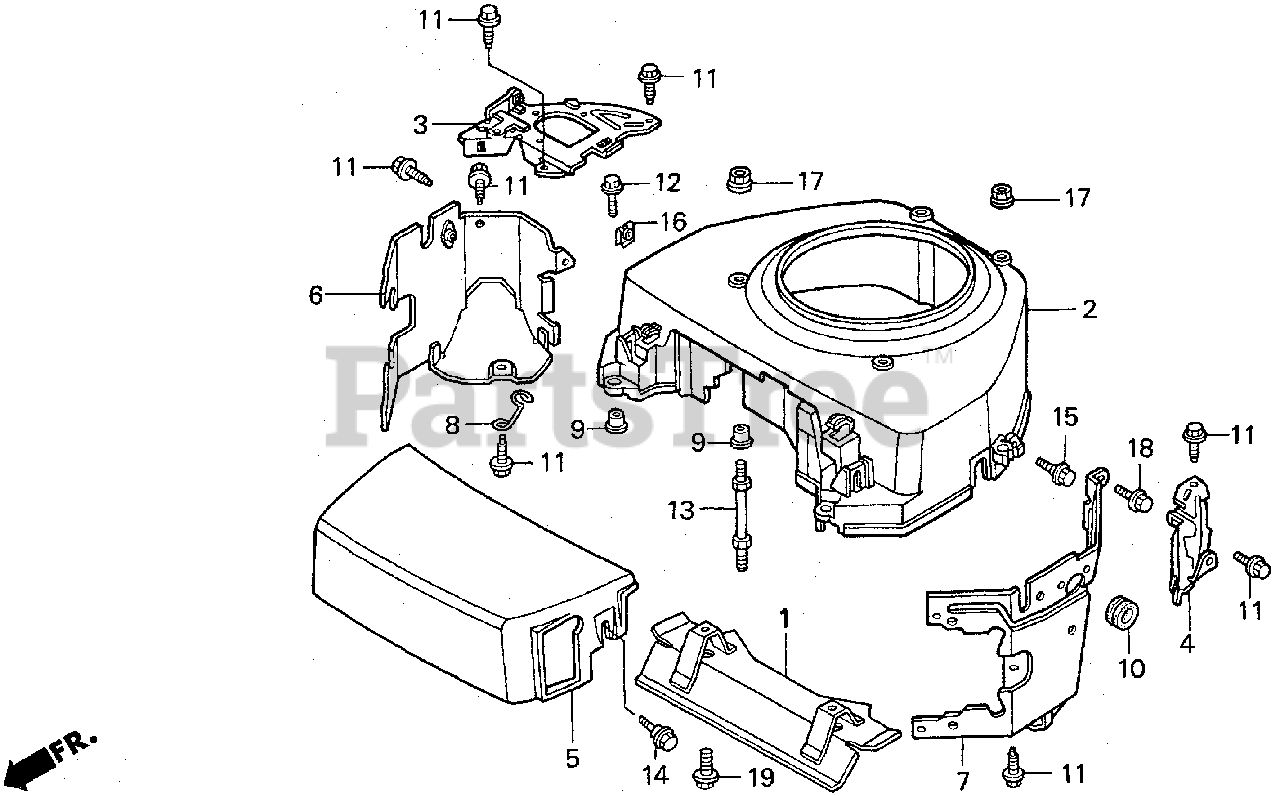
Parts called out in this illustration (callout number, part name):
1	PROTECTOR, EX. PIPE
2	COVER, FAN *R8* (RECOIL STARTER) (BRIGHT RED)
2	COVER, FAN *NH1* (RECOIL STARTER) (BLACK)
2	COVER, FAN *R280* (RECOIL STARTER) (POWER RED)
3	PLATE, R. SIDE
4	PLATE, L. SIDE
5	HOOD, FAN COVER
6	SHROUD, R.
7	SHROUD, L.
8	CLAMP, IGNITION TUBE
9	COLLAR B, TAILLIGHT
10	RUBBER, BRACKET MOUNTING
11	BOLT, FLANGE (6X12) (CT200)
12	BOLT, FLANGE (6X23)
13	BOLT, STUD (6X76)
14	BOLT, FLANGE (6X20)
15	BOLT, FLANGE (6MM) (BLACK)
16	NUT, SPRING (6MM)
17	NUT, FLANGE (6MM)
18	BOLT, FLANGE (6X8)
19	BOLT, FLANGE (8X16)
